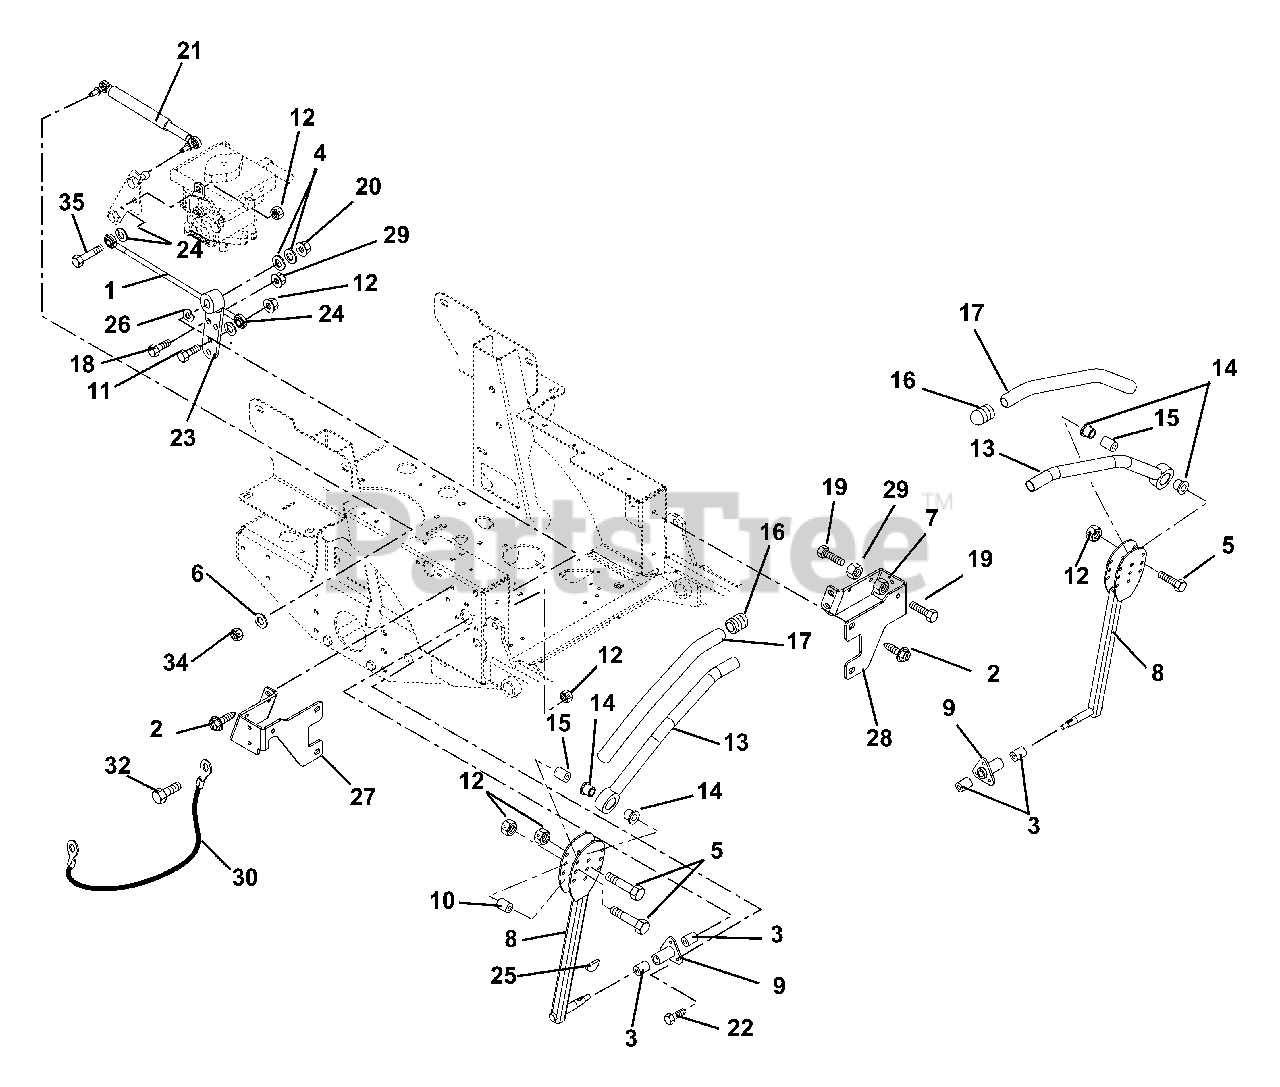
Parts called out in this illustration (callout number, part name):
1	Assembly, Steering Rod
2	Screw, Tapping .38-16 x .75 Hex Washer Head
3	Bushing .625 x .75 x .50
4	Washer, Flat Steel .406 x .812 x .065
5	Bolt, Hex .31-18 x 1.75 Grade 5
6	Washer, Flat Steel .328 x 1.00 x .094
7	Nut, Hex Jam .375-16
8	Control Arm
9	Housing, Bushing
10	Eccentric
11	Bolt, Hex .31-18 x 1.25 Grade 5
12	Nut, Nyloc Flange 3/8-18
13	Handle Weldment Left-Hand
13	Handle Weldment Right-Hand
14	Bushing, Flange Nylon .762 x 1.48 x .44
16	Caplug, Handlebar
17	Grip, Handlebar
18	Bolt, Hex .375-16 x 1.75
19	Bolt, Hex .38-16 x 1.25 Grade 5
20	Nut, Nyloc Flange 3/8-16
22	Bolt, Hex .31-18 x 1.00 Grade 5
23	Weldment, Pivot Arm
24	Washer, Locking .31 x .078 Regular
25	Key, Woodruff .13 x .63
26	Wave Washer
27	Stop, Steering-Right Hand
28	Stop, Steering-Left Hand
29	Nut, Locking Jam Center .375-16
30	Cable, Hood
31	Washer, Flat Steel .265 x .50 x .087
32	Bolt-Hex .25-20 x .75 Grade 5
33	Nut, Nyloc Flange .25-20
34	Nut, Locking Nylon M8-1.25
35	Bolt, Hex .31-18 x 1.50 Grade 5
